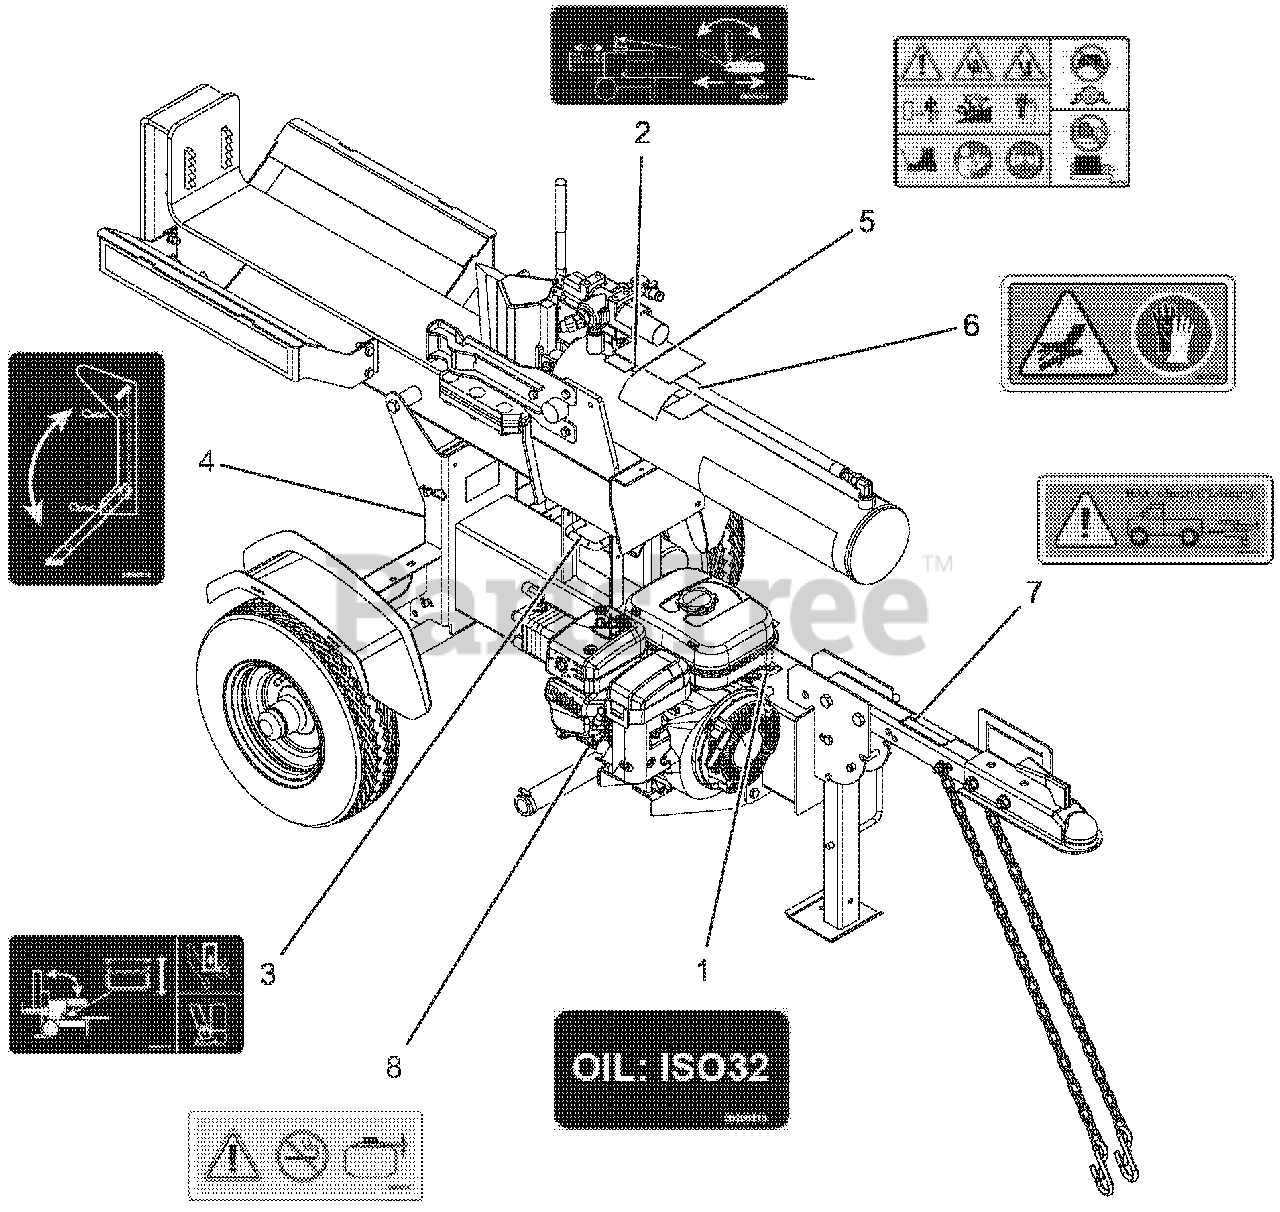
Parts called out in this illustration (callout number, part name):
1	DECAL, LOG SPLITTER-HYD OIL
2	DECAL, LOG SPLITTER-RAM OP
3	DECAL, LOG SPLITTER-TILT OP
4	DECAL, LOG SPLITTER-REAR STAND
5	DECAL,DANGER LOG SPLITTER
6	DECAL,HYD WARNING
7	DECAL,TOWING
8	DECAL,FUEL WARNING
